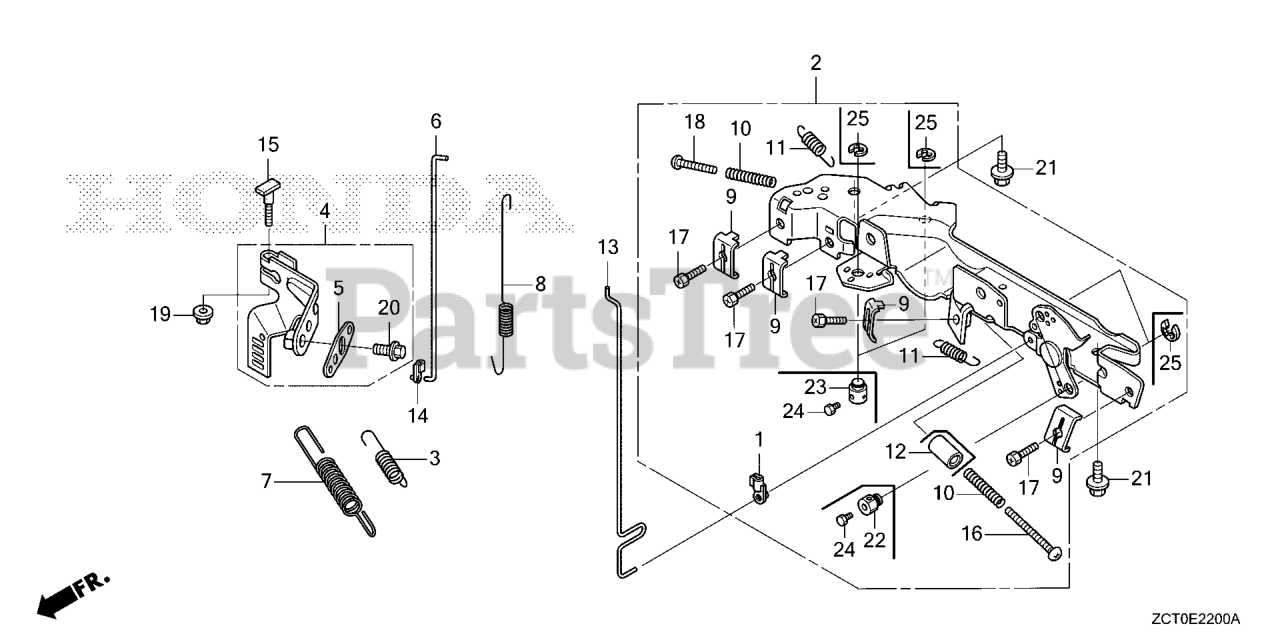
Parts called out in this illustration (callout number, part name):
1	JOINT, ROD
2	CONTROL ASSY.
3	SPRING, STARTER
4	ARM, GOVERNOR
5	ARM, SUB
6	ROD, GOVERNOR
7	SPRING, GOVERNOR
8	SPRING, THROTTLE RETURN
9	HOLDER, CABLE
10	SPRING, CONTROL ADJUSTING Use from Engine SN 2327377.
11	SPRING, CABLE RETURN
13	ROD, CHOKE CONTROL
14	BUSH, LINKAGE
15	BOLT, GOVERNOR ARM
16	SCREW, PAN (5X45)
17	BOLT, RECESSED (5X16)
18	SCREW, PAN (5X30)
19	NUT, FLANGE (6MM)
20	BOLT, FLANGE (6X10)
21	BOLT, FLANGE (6X14)
22	HOLDER, WIRE
23	HOLDER, CABLE
24	BOLT, RECESSED (4X6)
25	E-RING (5MM)
